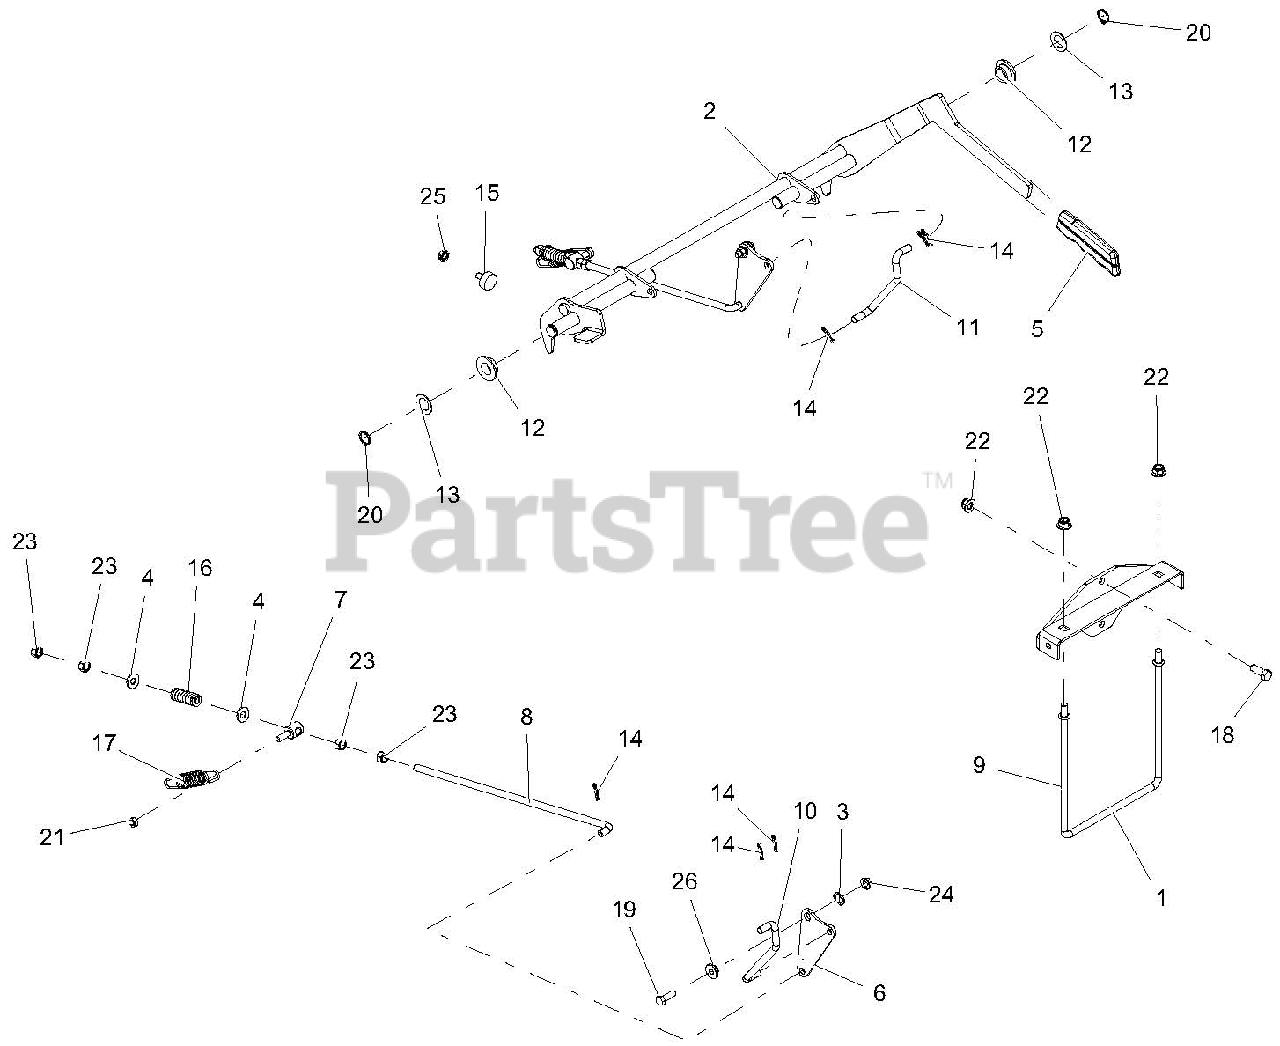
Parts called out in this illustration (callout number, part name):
1	WMT, SPRING ANCHOR BRKT-BLACK
2	WLDMT, PARKING BRAKE LEVER
3	WAVE WASHER .531X.781X.125 FH
4	WSHR-FL-STL.38X.875X.083 YWZC
5	GRIP, PARKING BRAKE
6	PLATE, BRAKE PIVOT-BLACK
7	TRUNNION, .31-18
8	ROD, BRAKE ADJ.
9	ROD, BRAKE MTG
10	LINKAGE, RH BRAKE ACTUATING
11	LINKAGE, LH BRAKE ACTUATING
12	BSHG, FLANGE .762 X 1.48 X .44 NYLON
13	WSHR-HDND-THRST
14	PIN-HAIR, ENDRIES #25 YWZC
15	BUMPER, RUBBER
16	SPRG, COMPRESSION
17	SPRG, TENSION .105 X .850 X 4.880
18	BLT-HEX .38-16X1.00 GR5 YWZC
19	BLT-HEX .31-18X1.00 GR5 YWZC
20	RG-RTNG-EXT .750x.078
21	@NUT-LK-CTR-JAM .31-18 YWZC
22	NUT-LK-NYL-FLG .38-16 YWZC
23	NUT-HEX .38-16 YWZC
24	NUT, LK-TOP-FLG .312-18 YWZC
25	@NUT-SPNLK-FLG .312-18 YWZC
26	BSHG, FLG .32X.500.344X.880
